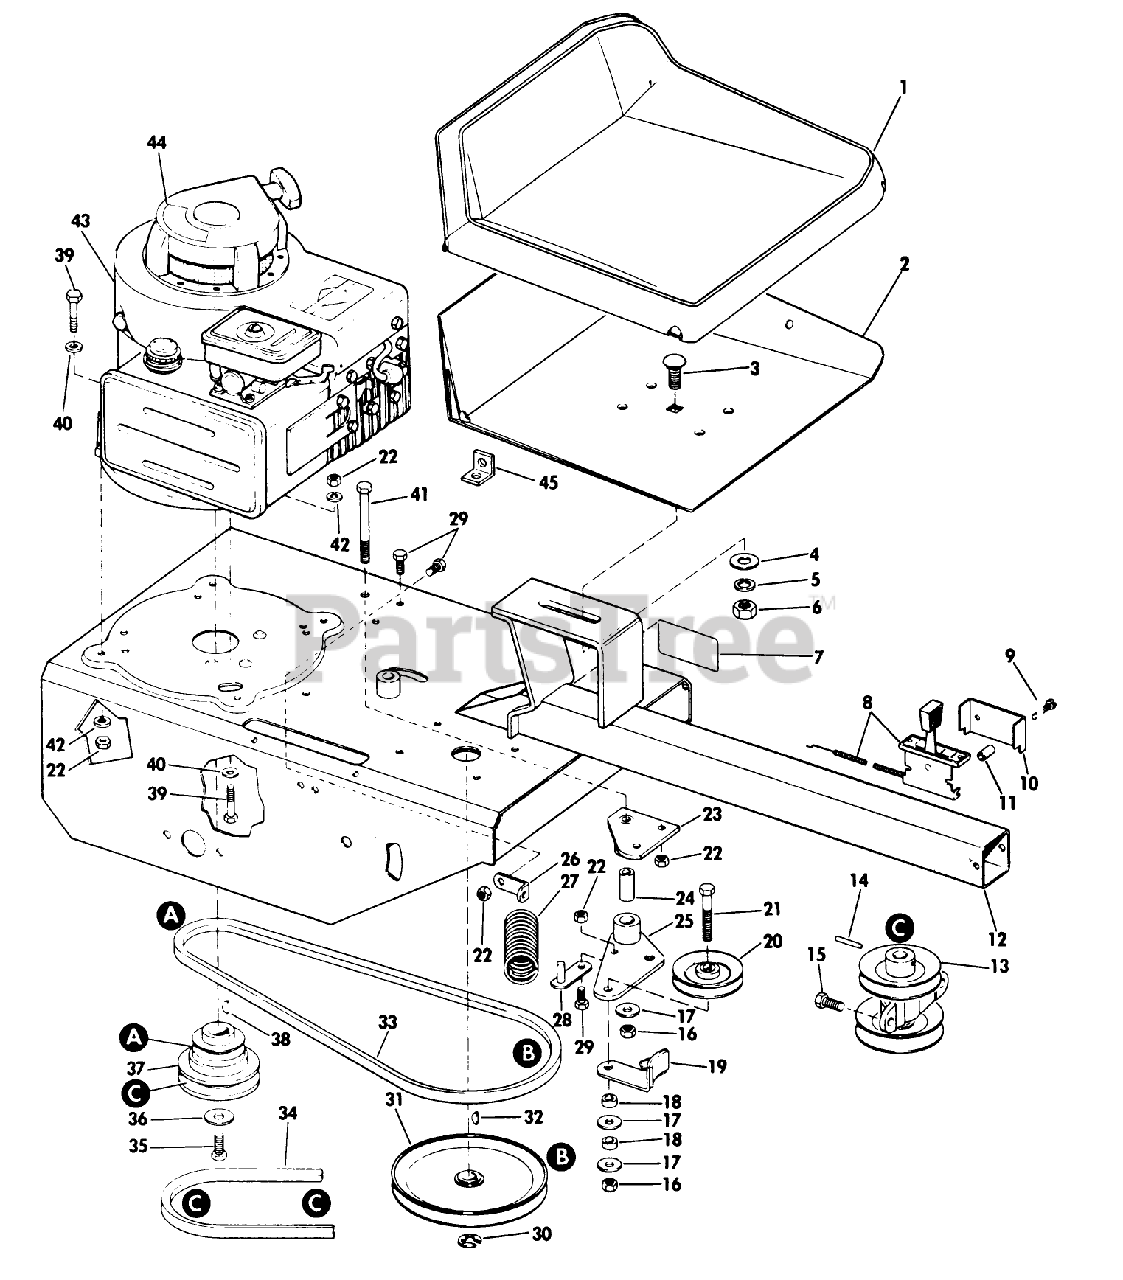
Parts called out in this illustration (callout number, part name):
7	Plate-Model No.
16	LOCKNUT
43	Engine-5 HP Briggs and Stratton-Model 130902
